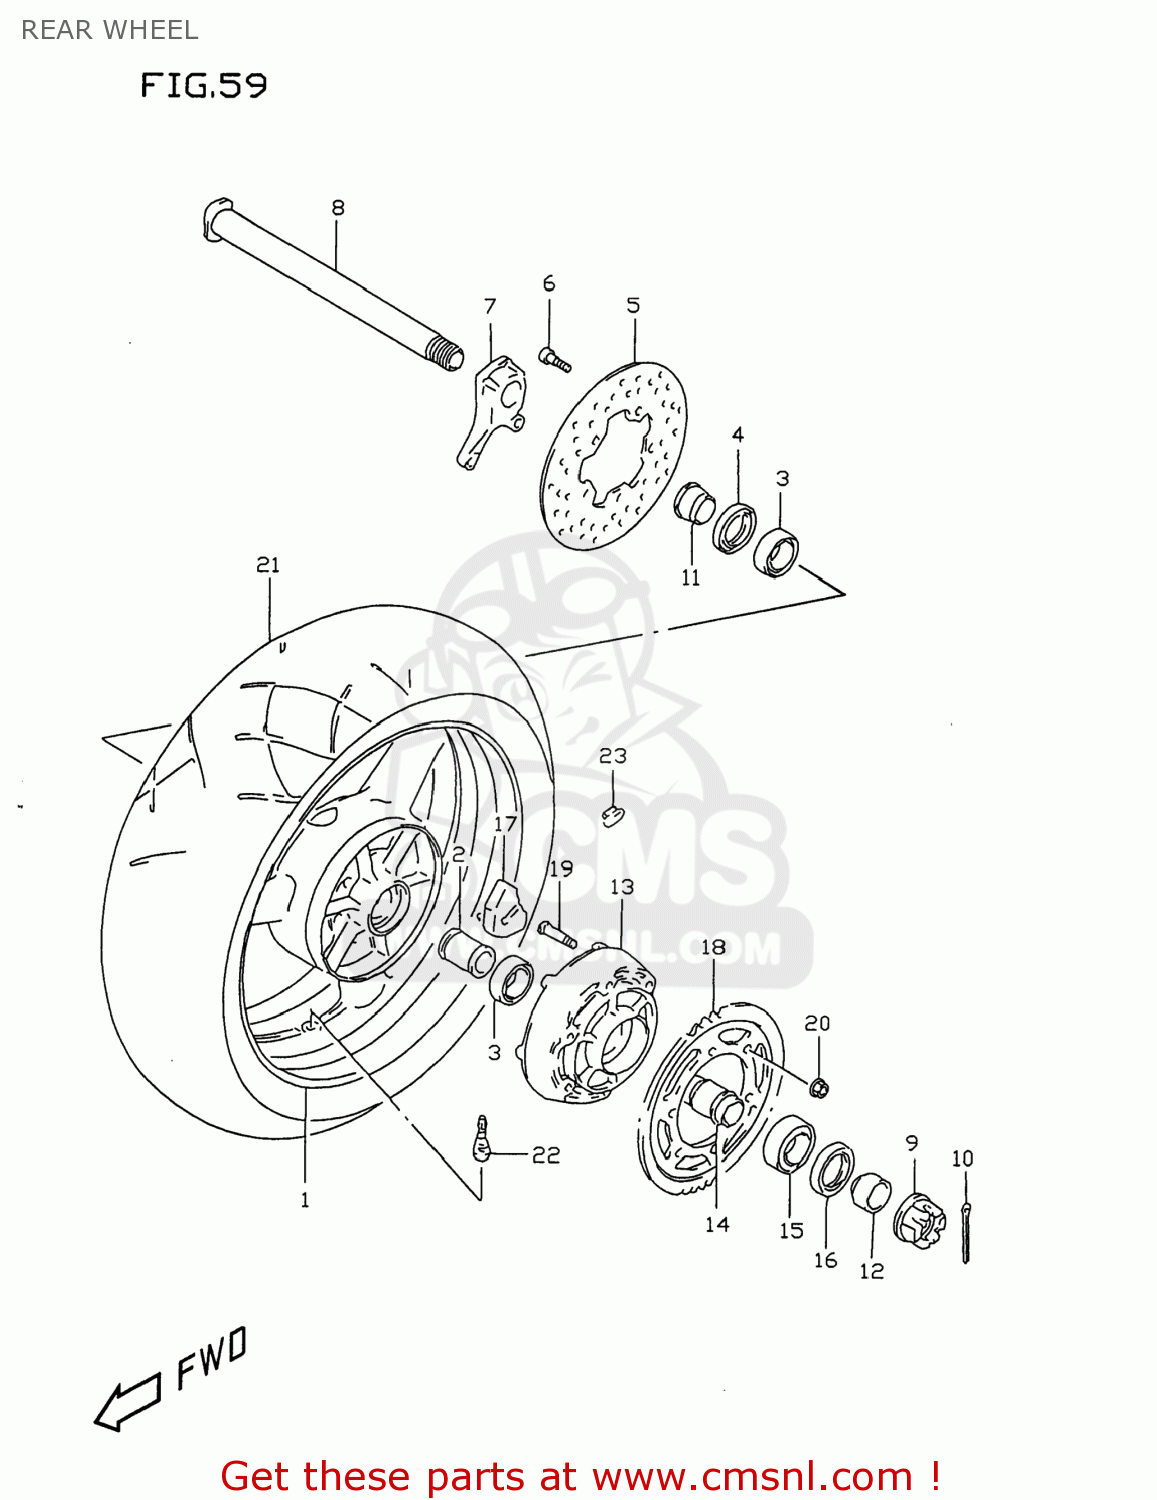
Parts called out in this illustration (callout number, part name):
1	WHEEL,REAR (17XMT6.00)(S
2	SPACER,RR HUB BEARING
3	BEARING(32X58X13)
4	SEAL,OIL(38X58X7)
5	DISC,RR BRAKE
6	BOLT 8X33
7	BRACKET,RR CALIPER
8	AXLE,RR
9	NUT
10	PIN, COTTER
11	SPACER,RR AXLE,R
12	SPACER,RR AXLE,L
13	DRUM,REAR SPROCKET MOUNT
14	RETAINER,RR SPROCKET DRUM
15	BEARING
16	SEAL,OIL(39X65X7)
17	ABSORBER,RR HUB SHOCK
18	SPROCKET,RR(NT:43)
19	BOLT
20	NUT
21	TIRE,REAR 190/50 ZR17
22	VALVE ASSEMBLY,WHEEL,TR412
23	BALANCER,WHEEL (10G)
